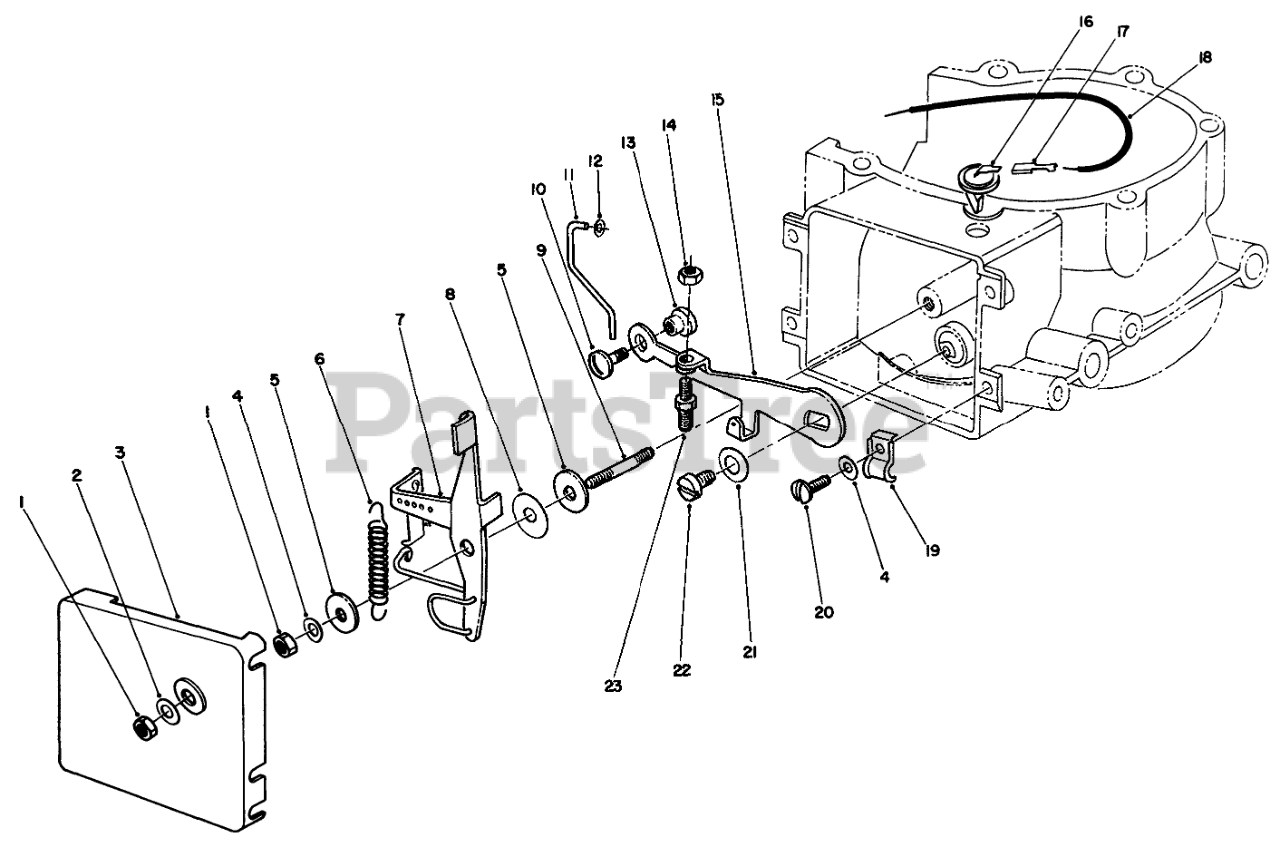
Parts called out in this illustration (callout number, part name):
2	Washer
3	Cover-Governor Housing
4	Washer-Spring
5	Washer
6	Spring
7	Lever
8	Disc-Brake
10	Capscrew
11	LINKAGE
12	Washer-Tab
13	Shield
15	Lever
16	Connector Assembly
17	Connector-Spade
19	Clamp
20	Screw
21	Washer-Spring
22	Screw
23	Damping Spring Assembly
